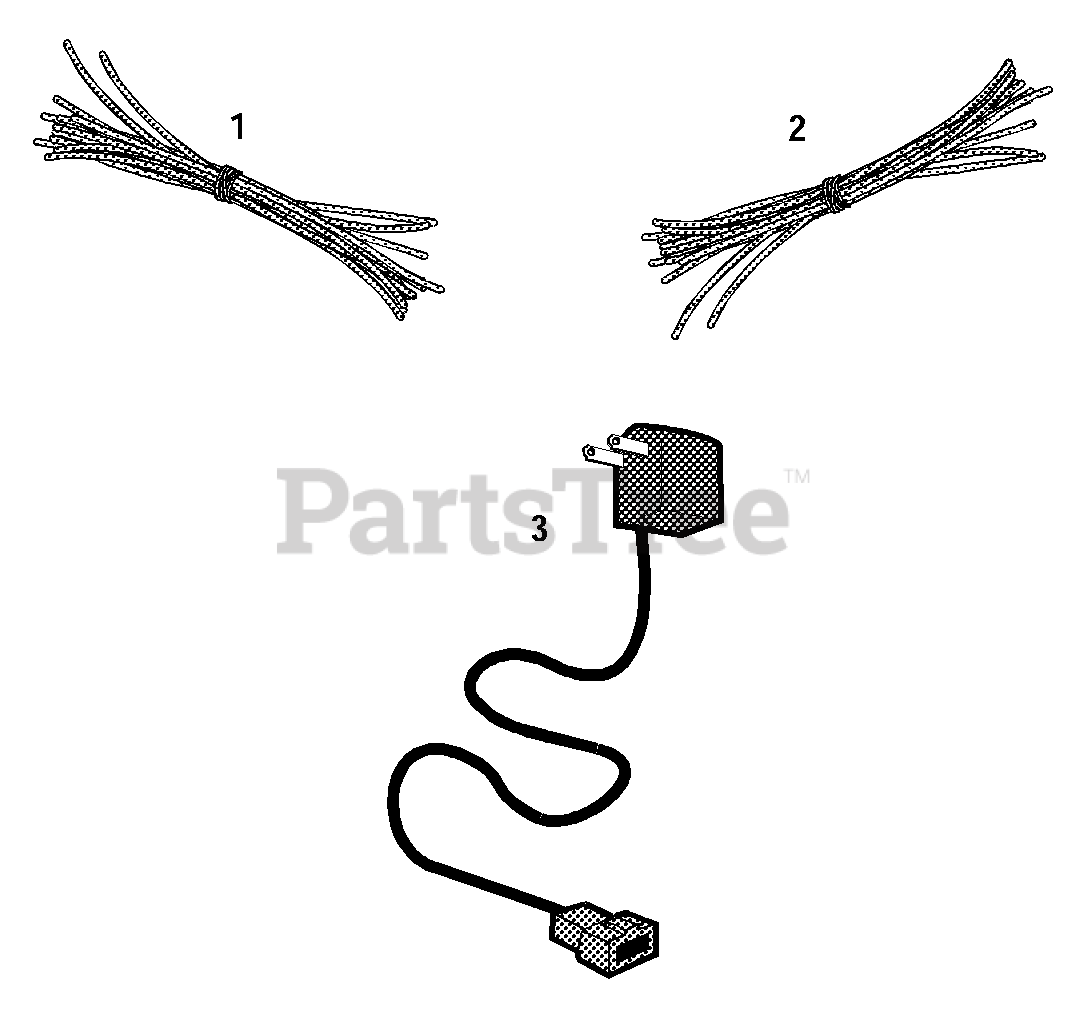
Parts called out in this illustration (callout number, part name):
1	Trimmer String Kit, .155" diameter line (24 pieces)
2	Trimmer String Kit, .130" diameter line (24 pieces)
3	Battery Charger (for electric start model)
